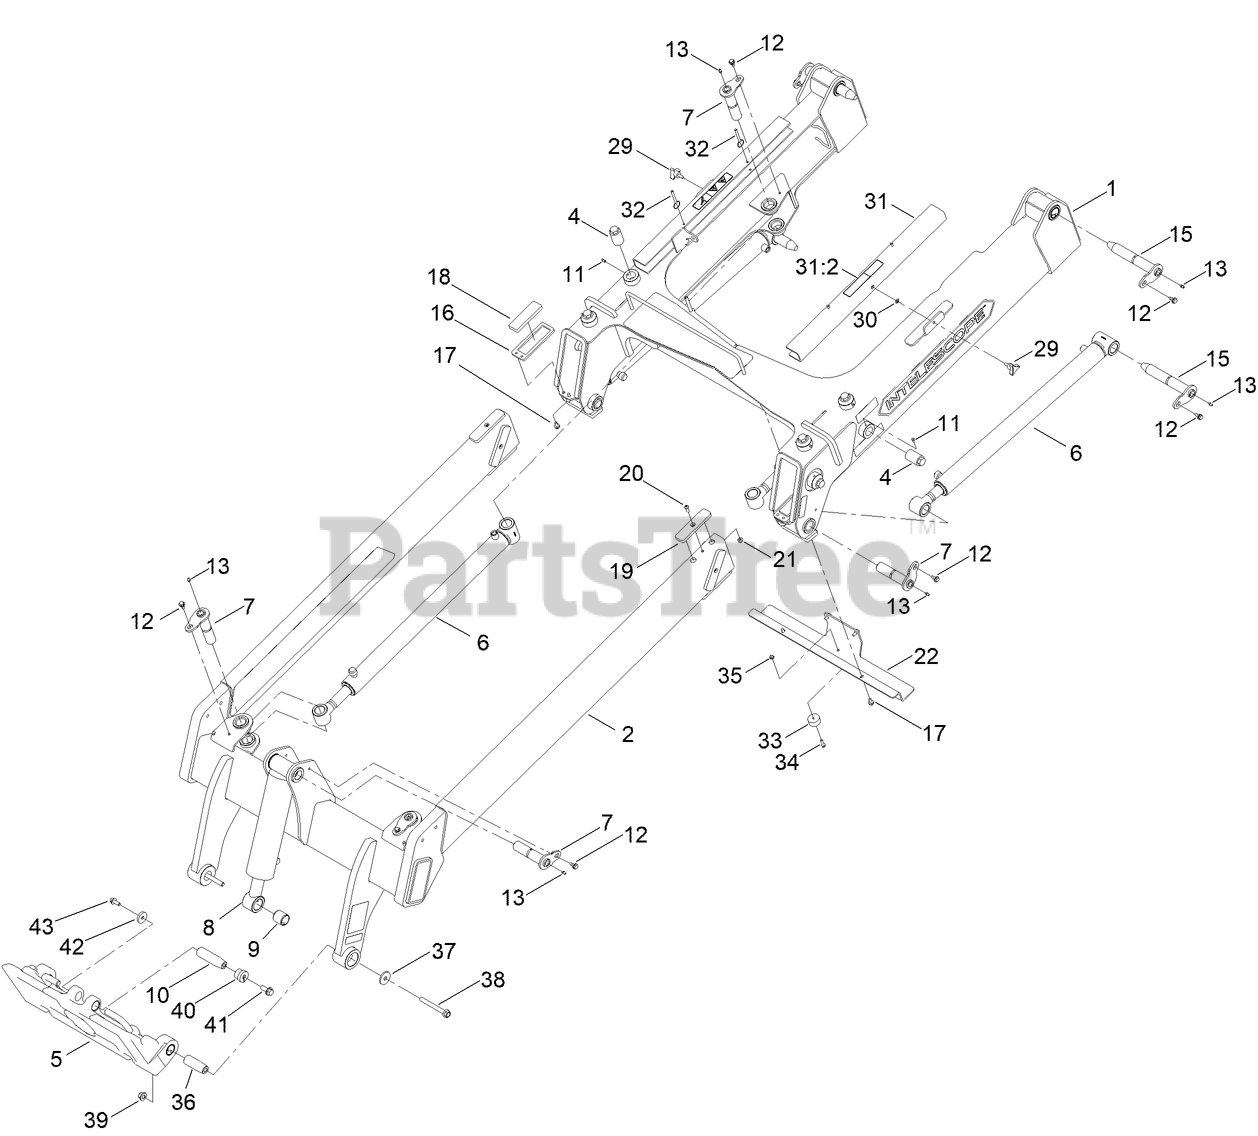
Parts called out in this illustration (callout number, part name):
1	LOADER ARM-UPPER, ASM
2	LOADER ARM-LOWER, ASM
4	SCREW-SLIDE,ADJUSTMENT
5	ATTACHMENT PLATE ASM
6	HYD CYLINDER ASM
7	FLAG PIN ASM
8	CYL-HYD
9	BUSHING-SPRING
10	PIN-TAPERED
11	SCREW-SET, SQH
12	BOLT-SHOULDER
13	FITTING-GREASE
15	PIVOT PIN ASM
16	RETAINER-PAD
17	SCREW-HWHTF
18	STRIP-SLIDE,LOWER
19	STRIP-SLIDE,
20	SCREW-HSBH
21	NUT-HF, NI
22	GUARD-HYDRAULICS
30	RING-RETAINING, BOLT
31	LOCK-ARM
31:2	DECAL-DANGER
32	PIN-COTTERLESS
33	BUMPER-RECESSED
34	SCREW-HHF
35	NUT-HF
36	PIN-LINK,TAPER
37	WASHER-THRUST
38	SCREW-HHF
39	NUT-LOCK
40	INSERT-TAPERED
41	SCREW-HHF
42	WASHER-CLUTCH
43	SCREW-HHF
